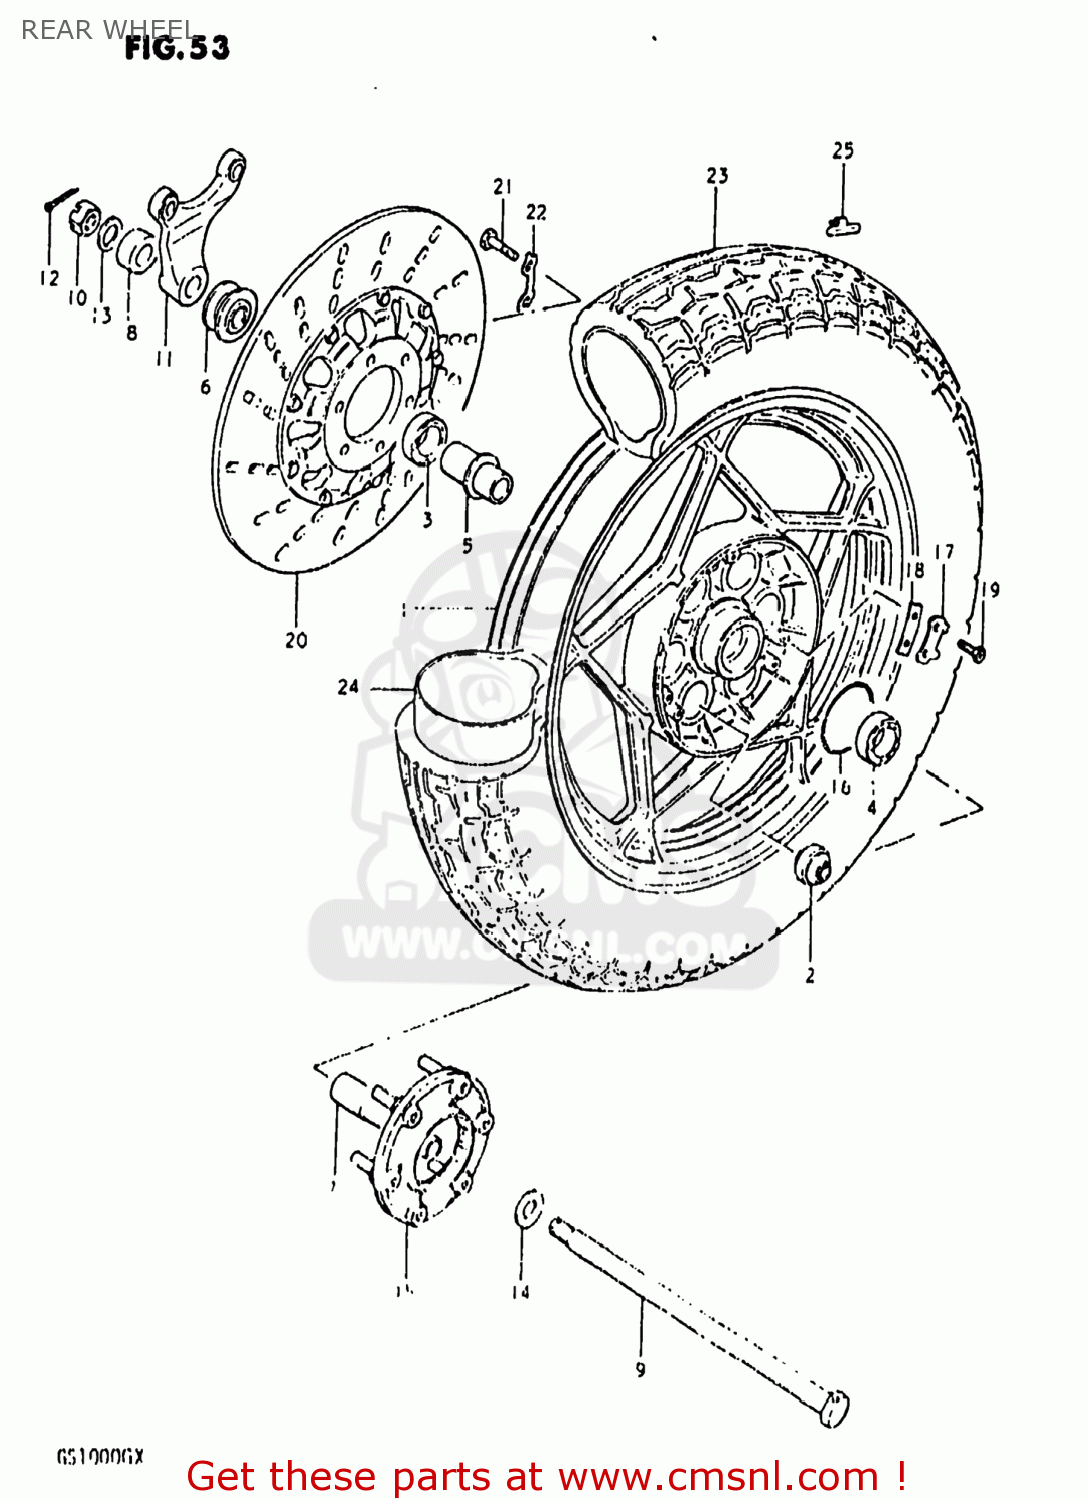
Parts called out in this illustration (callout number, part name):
1	CASTING WHEEL,REAR
2	BUSH
3	BEARING
4	BEARING
5	SPACER,REAR HUB BEARING
6	SPACER,REAR AXLE
7	SPACER,REAR AXLE,LEFT
8	SPACER (17X33X15.2)
9	AXLE,REAR
10	NUT
11	BRACKET,RR,CALIPER
12	PIN,COTTER
13	WASHER
14	WASHER (17.5X36X3.2)
15	JOINT ASSEMBLY,REAR HUB DRUM
16	O RING(D:2.1,ID:65)
17	WASHER
18	WASHER,THRUST(T:1.6)
19	SCREW
20	DISC,RR BRAKE
21	BOLT(8X30)
22	WASHER
23	TIRE
24	TUBE ASSEMBLY,WHEEL,INNER
25	BALANCER,WHEEL
